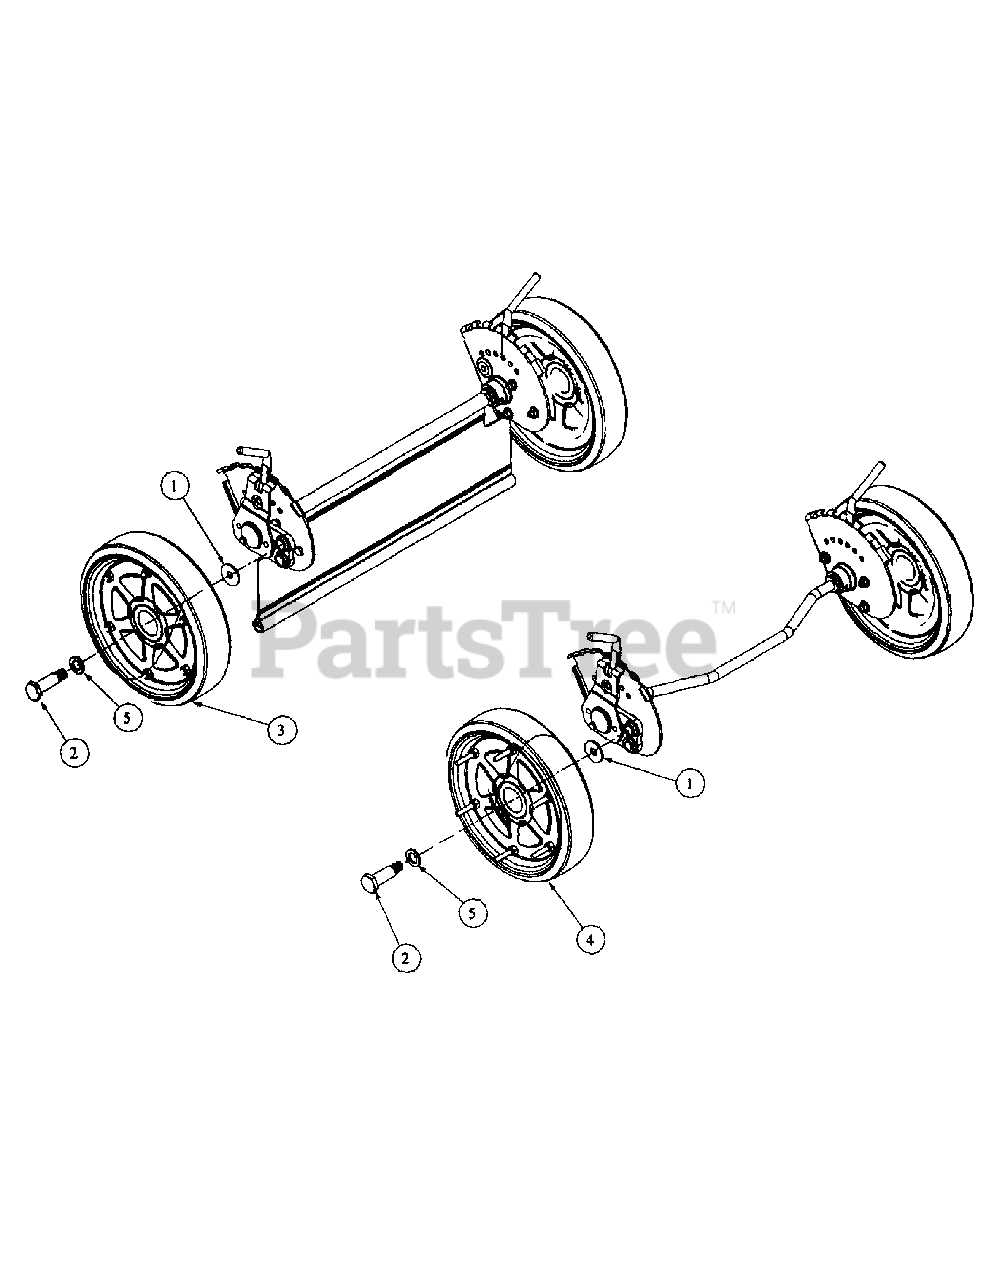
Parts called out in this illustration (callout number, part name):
1	Washer, 1/2 x 1 Shim
2	Shoulder Screw, 58 x 1.48, 1/2-20
3	Wheel, 9 x 2 .125 With drive Gear
4	Wheel, 9 x 2 .125 With drive Gear
5	Washer, .625 x .875 x .031
